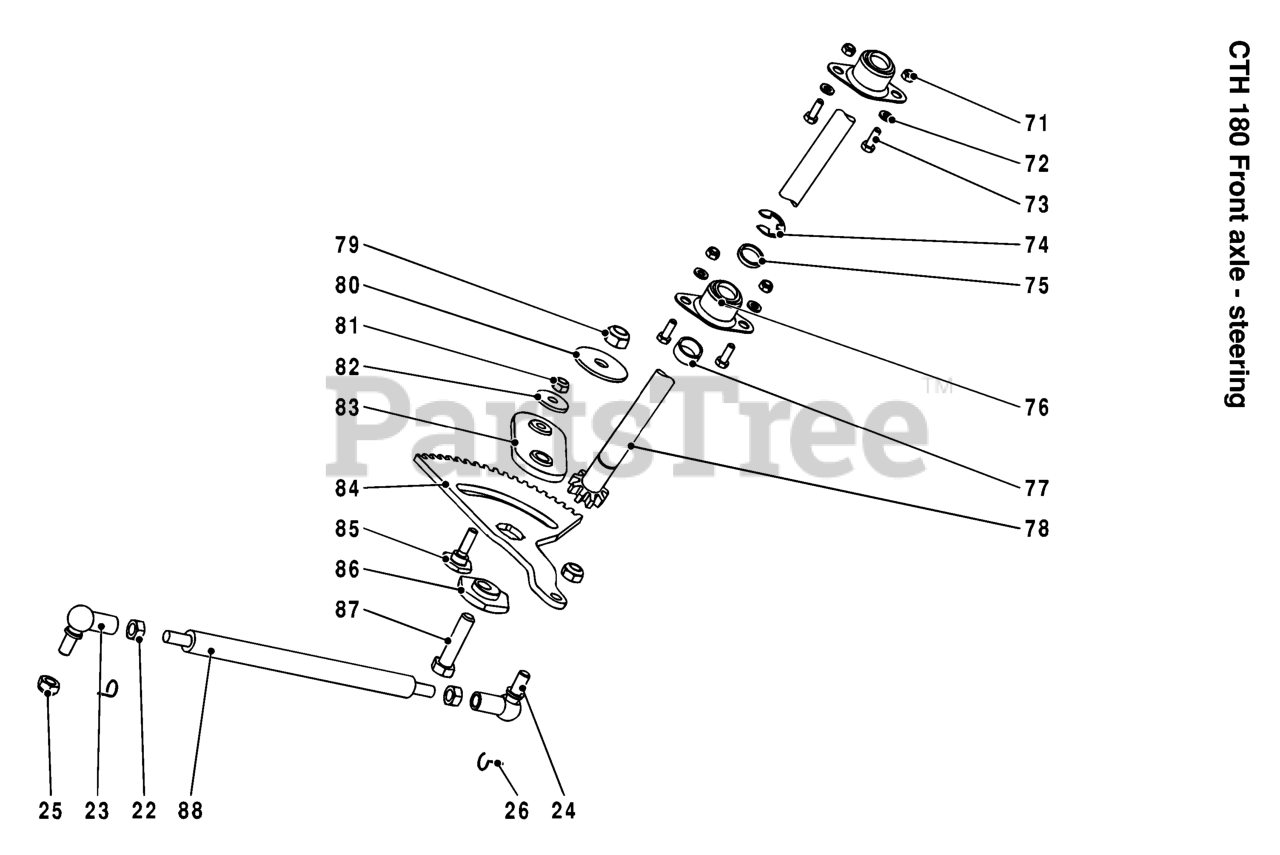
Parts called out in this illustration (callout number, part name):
23	BALL JOINT
24	BALL JOINT
71	NUT
74	RETAINING RING
81	NUT
84	GEAR SECTOR
